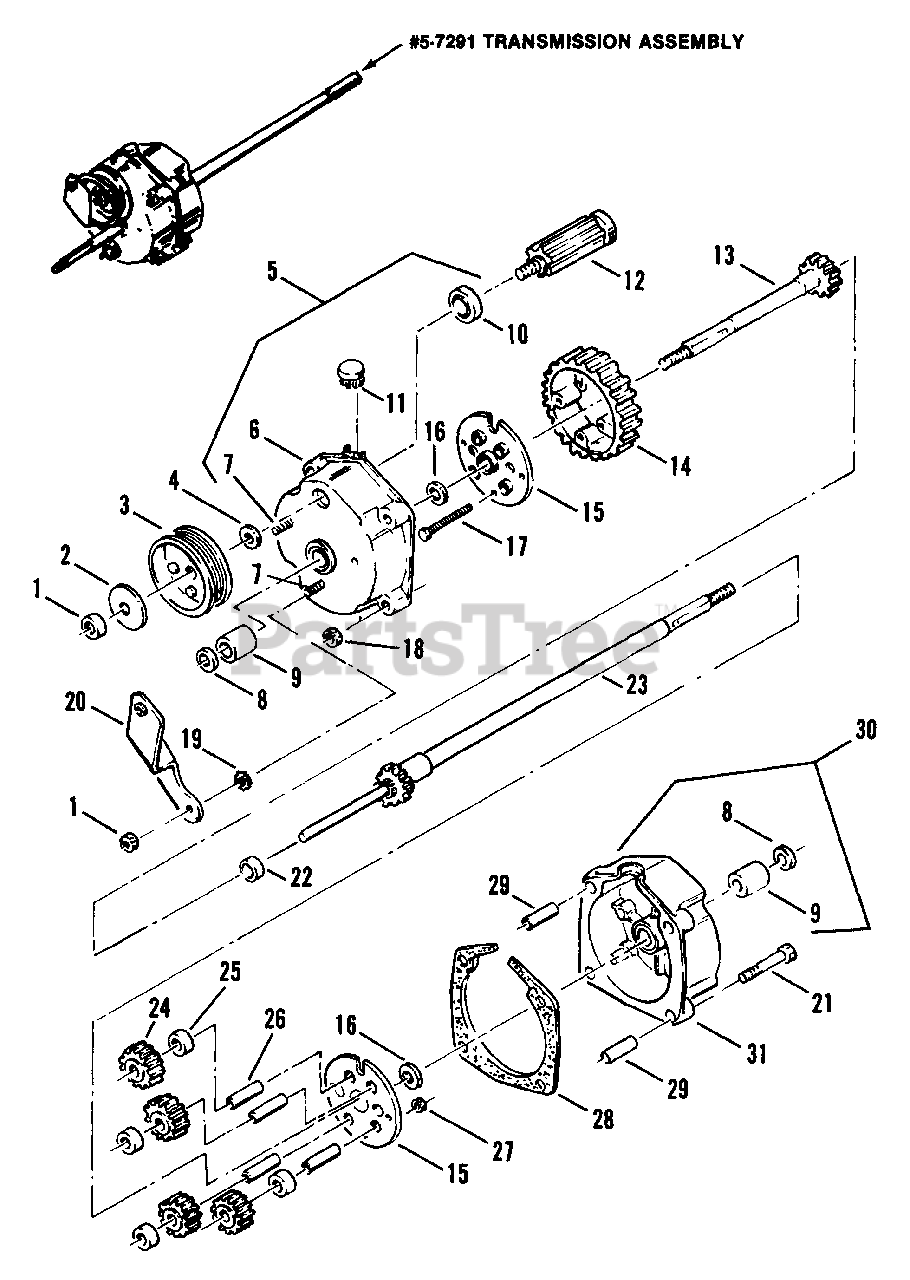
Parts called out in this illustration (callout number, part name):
1	NUT, 5/16-24 Hex Lock
2	WASHER, Spring
3	PULLEY, Poly-Vee Belt
4	WASHER, Spring
5	HOUSING ASSEMBLY, Right
5-7291	ASSEMBLY, Transmission
6	HOUSING, Right Side
7	SCREW, 5/16-24x1-1/8" Rib Neck
8	SEAL, 5/8" ID
9	BEARING, Differential
10	BEARING, Ball
11	PLUG, Housing
12	GEAR, Input
13	AXLE, Short
14	GEAR, Differential, 46 Tooth
15	PLATE
16	WASHER, Thrust
17	SCREW, 10-32 x 1-1/2" Hex Head Cap
18	NUT, 1/4-28 Hex Lock
19	WASHER, 5/16" Internal External Tooth Lock
20	BRACKET, Differential
21	SCREW, 1/4-28 x 1-3/8 Hex Head Cap
22	SPACER, Axle Gear
23	AXLE, Long
24	GEAR, Pinion, 12 Tooth
25	SPACER, Pinion Gear
26	SHAFT, Pinion
27	NUT, 10-32 Hex Lock
28	GASKET, Housing
29	PIN, 3/8-7/16" Roll
30	HOUSING ASSEMBLY, Left
31	HOUSING, Left Side
